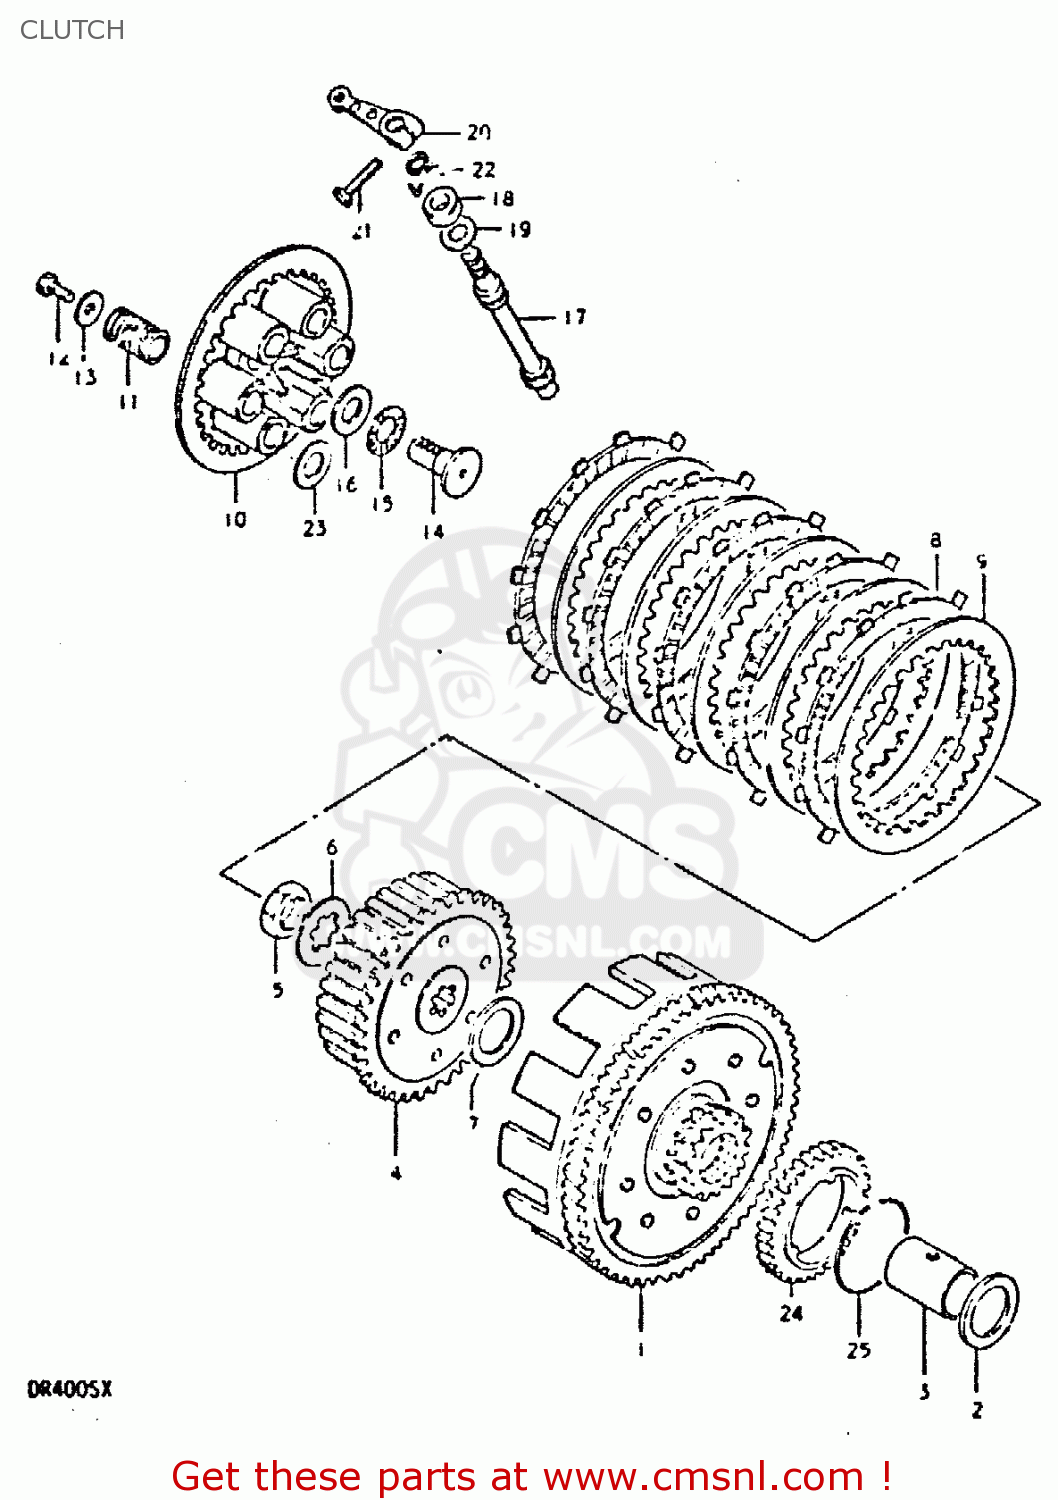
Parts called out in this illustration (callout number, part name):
1	GEAR ASSEMBLY,PRIMARY DRIVE
2	WASHER
3	SPACER
4	HUB,CLUTCH SLEEVE
5	NUT (20MM)
6	WASHER,LOCK
7	WASHER(20X38X2)
8	PLATE,CLUTCH DRIVE (MCA)
9	PLATE,CLUTCH DRIVEN (NAS)
10	DISC,CLUTCH PRESSURE
11	SPRING
12	BOLT, UPPER
13	WASHER
14	RACK,CLUTCH RELEASE
15	BEARING(15X28X2)
16	WASHER
17	PINION,CLUTCH RELEASE
18	OIL SEAL
19	20
20	ARM,CLUTCH RELEASE
21	BOLT,REAR
22	SPRING
23	WASHER
24	GEAR,OIL PUMP DRIVE
25	CIRCLIP
